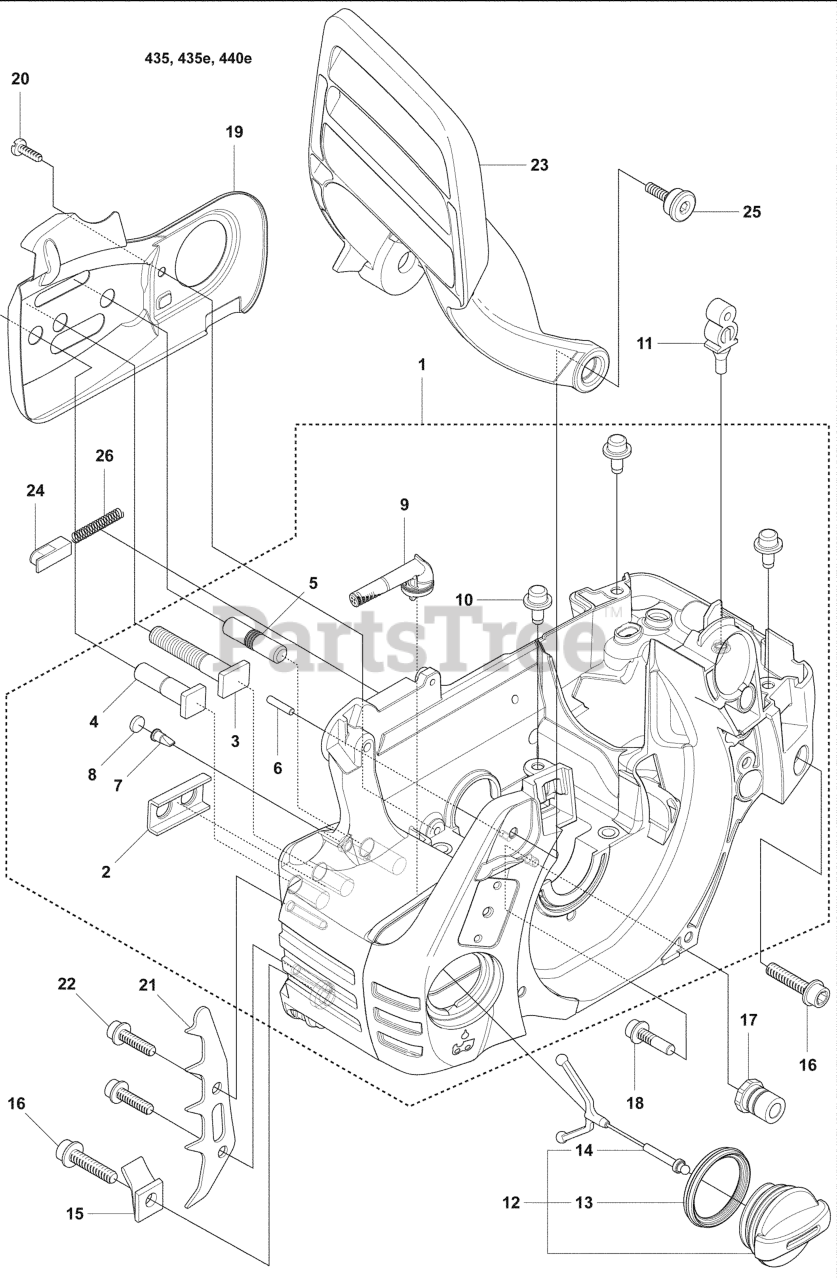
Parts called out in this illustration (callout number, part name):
1	CRANKCASE ASSY
2	STIFFENING PLATE
3	BAR BOLT
4	BAR BOLT
5	BAR BOLT
6	PIN
7	VALVE-CHECK (DUCKBILL)
8	PLUG
9	OIL SCREEN
10	GUIDE PEN
11	SUPPORT
12	TANK CAP ASSY
13	SEALING
14	TANK LOCK
15	CHAIN CATCHER
16	SCREW IHSCFT
17	LATERAL SUPPORT
18	SCREW IHSCFT
19	CHAIN GUIDE PLATE
20	SCREW
21	SPIKE INNER
22	SCREW
23	HAND GUARD
24	CATCH
25	SCREW
26	LOCK SPRING
